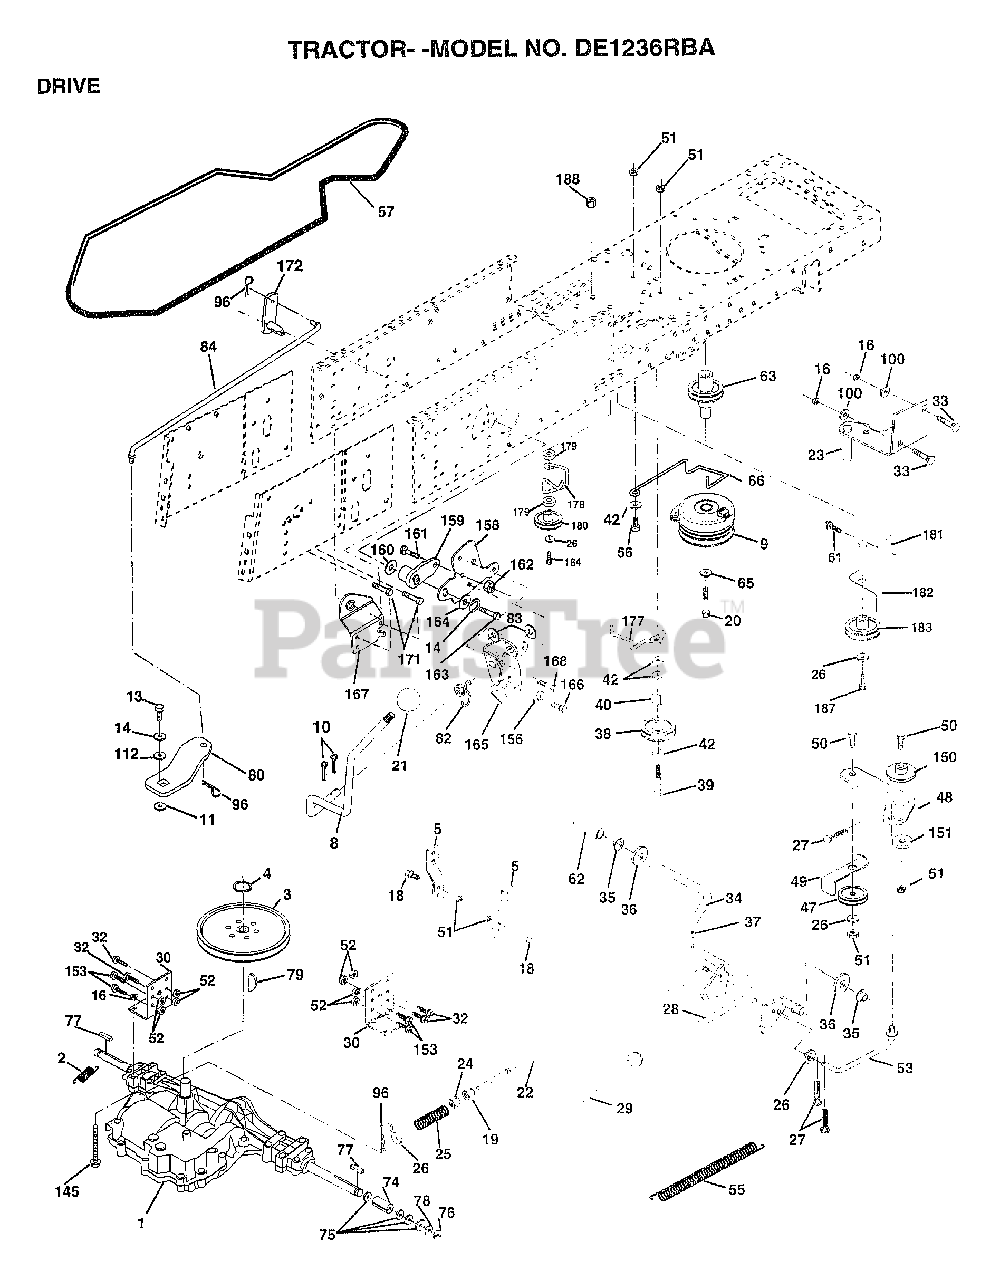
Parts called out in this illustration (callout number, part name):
2	SPRING.BRAKE.RETU
3	"PULLEY.TRANSAXLE.7"""
5	STRAP TORQUE
8	ROD.SHIFT.FENDER.ADJ.LT.CRD
9	CLUTCH.ELEC.EVX
10	PIN COTTER 1/8
11	WASH-SHFT PLT LT
13	BOLT.1/4-28.W/PAT
14	LOCKWASHER
16	NUT
18	BOLT
19	NUT
20	BOLT.7/16-20X4.25
21	KNOB T (1/2-HOLE)
22	ROD.BRAKE.PMST.CRD
23	BRACKET.CLUT.MTG.
24	NUT
25	SPRING ROD LT
26	WASHER
27	COTTER PIN
28	ROD.BRAKE.PARK.LT
29	PLUNGER CAP T
30	TRANSAXLE MTG BKT
32	BOLT
34	SHAFT.ASM.PEDAL.FOOT.CRD
35	NYLON BEARING
36	WASHER LT
38	PULLEY.FLAT.IDLER
39	BOLT
40	SPACER T
42	WASHER
48	BELLCRANK.CLUTCH
49	RETAIN BELT
53	"LINK, CLUTCH T"
55	"SPRING, RETURN LT"
57	"V-BELT.KEV.111"""
61	SCREW
62	PEDAL COVER T
63	PULLEY.CLUTCH.EVX
65	LOCKWASHER
66	KEEPER-BELT
74	SPACER AXLE
75	WASHER
76	E-RING LT
77	SQUARE KEY
78	WASHER
80	"ARM.SHIFT.20""TIRE"
81	ASM.SHAFT
82	"SPRING,TORSION"
83	WASHER
84	LINK.SHIFT.CRD
96	RETAINER M
100	WASHER M
112	WASHER LT
145	BOLT.HEX.FLGHD
150	BUSHING.BELLCRANK.GRD.DR
151	WASHER
156	WASHER.SRRTD.5/16
158	BRKT.SHIFT.MOUNT
159	HUB.SHIFT
160	WASHER
161	BOLT T
164	WASHER.5/8X.281X10GA
165	BRKT.PIVOT.LEVER
166	SCREW.5/16-18X5/8
167	BRKT.SUPT.SHIFT.CRD
168	BOLT.SHOULDER.5/16-18X.561
169	PLATE.FASTENING
171	SCREW LT
172	SHAFT.ASM.SHIFT.FRT.CRD
173	BKRT.HYDRO.BYPASS.CRD
177	KEEPOER.FLAT.IDLER
178	KEEPER.BELT.IDLER
179	WASHER
180	PULLEY.FLAT
181	BRKT.IDLER.GRD.DR.CRD
182	"KEEPER.BELT.2.5"".OD.CRD"
183	PULLEY.V-IDLER
184	SCREW.HXWSH.3/8
187	SCREW
